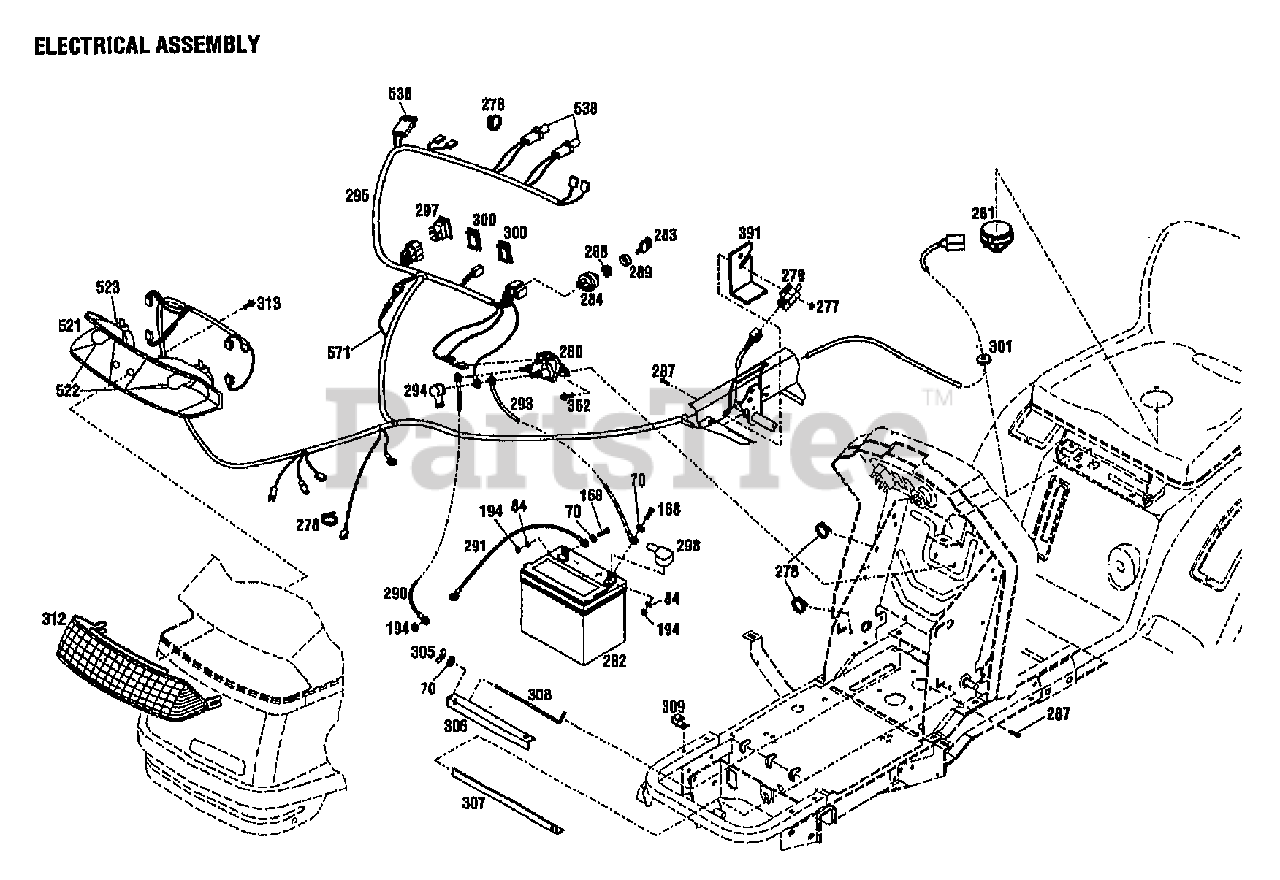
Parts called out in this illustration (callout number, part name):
70	WASHER-FLAT 1/4 SAE
84	WASHER-LK .25 ZP
168	SCR-HH 1/4-20X.75 G5 ZP
194	NUT-HEX 1/4-20 ZP
277	NUT W/LKWASHER 10-24 ZP
278	TIE-CABLE NYLON BLACK
279	SWITCH
280	SOLENOID
281	SWITCH-SEAT
282	BATTERY
283	KEY-IGNITION
284	SWITCH-IGNITION
287	SCR-HHS 10-24X.625 ZP
288	NUT-SWITCH
289	CAP-SWITCH
290	CABLE-STARTER
291	CABLE-BATTERY (-)
293	CABLE-BATTERY
294	BOOT-SOLENOID
295	HARNESS-WIRING
297	SWITCH-PTO
298	BOOT-TERMINAL
300	COVER-SWITCH
301	GROMMET
305	NUT-WING
306	CLAMP-BATTERY
307	BRKT-BATTERY LOWER
308	SCR-HOOK
309	CLIP-J
312	LENSE-HEADLIGHT
362	SCR 1/4-20X.5 FL SELF TAP
391	BRACKET-SWITCH
521	ASSM-HEADLIGHT
522	LIGHTBULB
523	SOCKET
536	FUSE
538	LIGHTBULB
571	ASSM-DIODE
